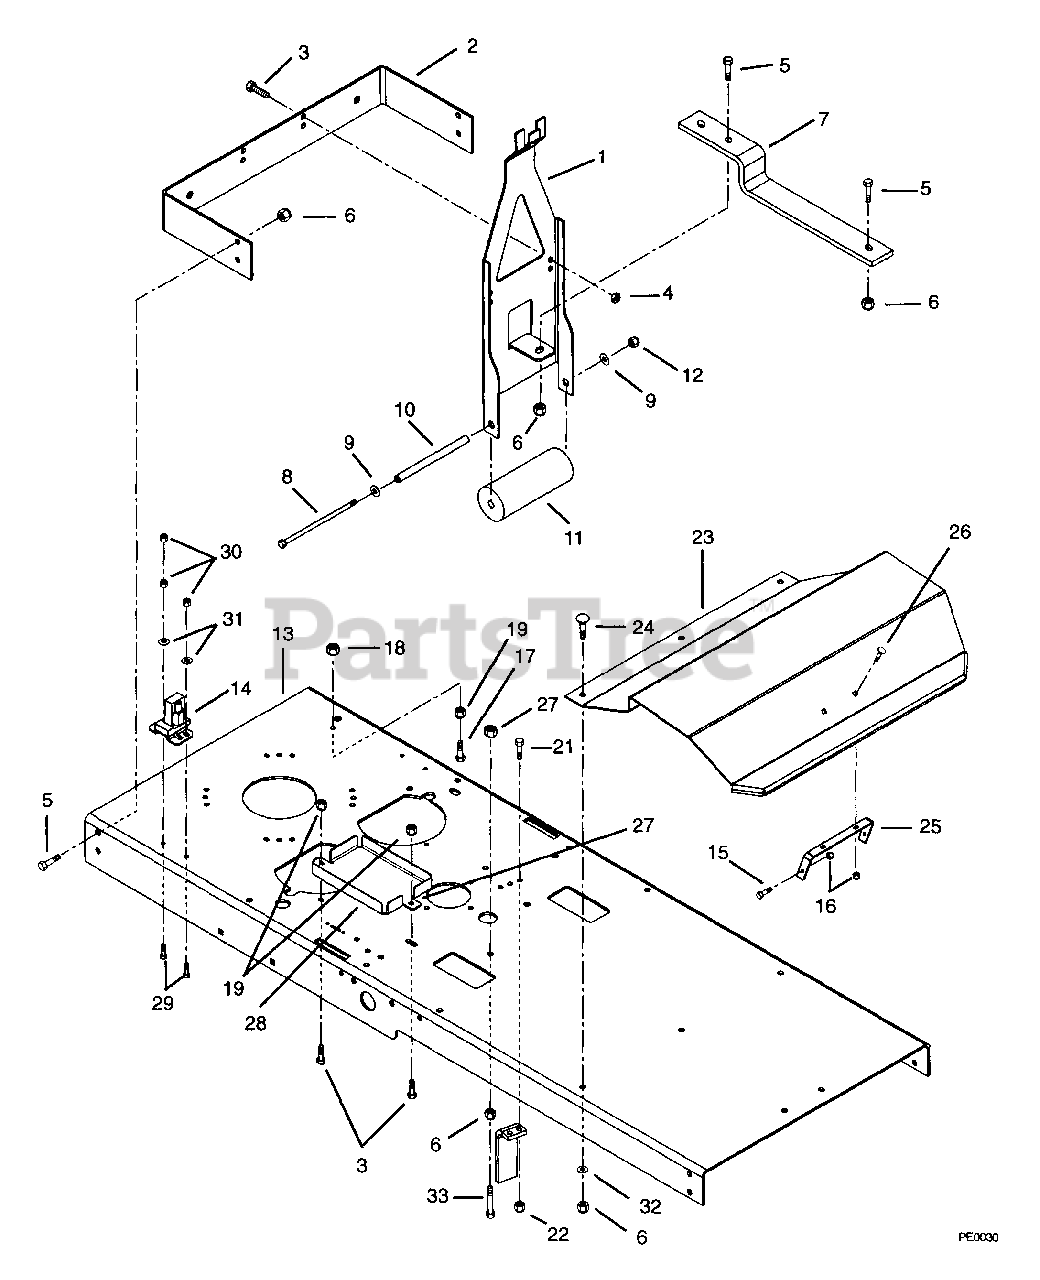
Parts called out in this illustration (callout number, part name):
1	ROLLER/SHROUD SUPPORT
2	BRACKET, ENGINE GUARD
3	BLT-HEX .31-18X.75 PL GR5
4	NUT-LK .312-18 GR A PL
5	BLT-HEX .38-16X1.00 PL GR5
6	NUT-LK-NYL .375-16 PL
7	BRACE, WHEELIE BAR
8	BLT-HEX .50-13X8.00
9	WSHR-FL-STL .531X1.062X.095
10	SPACER .509X.625X7.00
12	NUT-LK .50-13 HEX TYPE N
14	SOLENOID
15	BLT-HEX .25-20X.75 PL GR5
16	NUT-LK-NYL .250-20 PL
17	BLT-HEX .31-18X2.00 PL GR5
18	NUT-HEX .312-18
19	NUT-LK-NYL.312-18 PL
20	BRACKET, CLUTCH STOP
21	BLT-HEX .31-18X1.00 PL GR5
22	NUT-LK-NYL.312-18 PL
23	FOOT REST
24	BLT-RDHDSQNK .38-16X1.0 GR5PL
25	BRACKET, FOOTREST
26	BLT-RDHDSQNK .25-20X.75 GR5PL
27	NUT-HEX .375-16
28	BATTERY TRAY
29	SCREW,HEX HEAD WZ LK #10X.75
30	NUT-LK DUAL FACE 10-24 PL
31	WSHR-FL-STL.281X.62X.065 PL
32	WHSR-FL-.380X.875X.160
33	BLT-HEX .38-16X3.25 PL GR5
